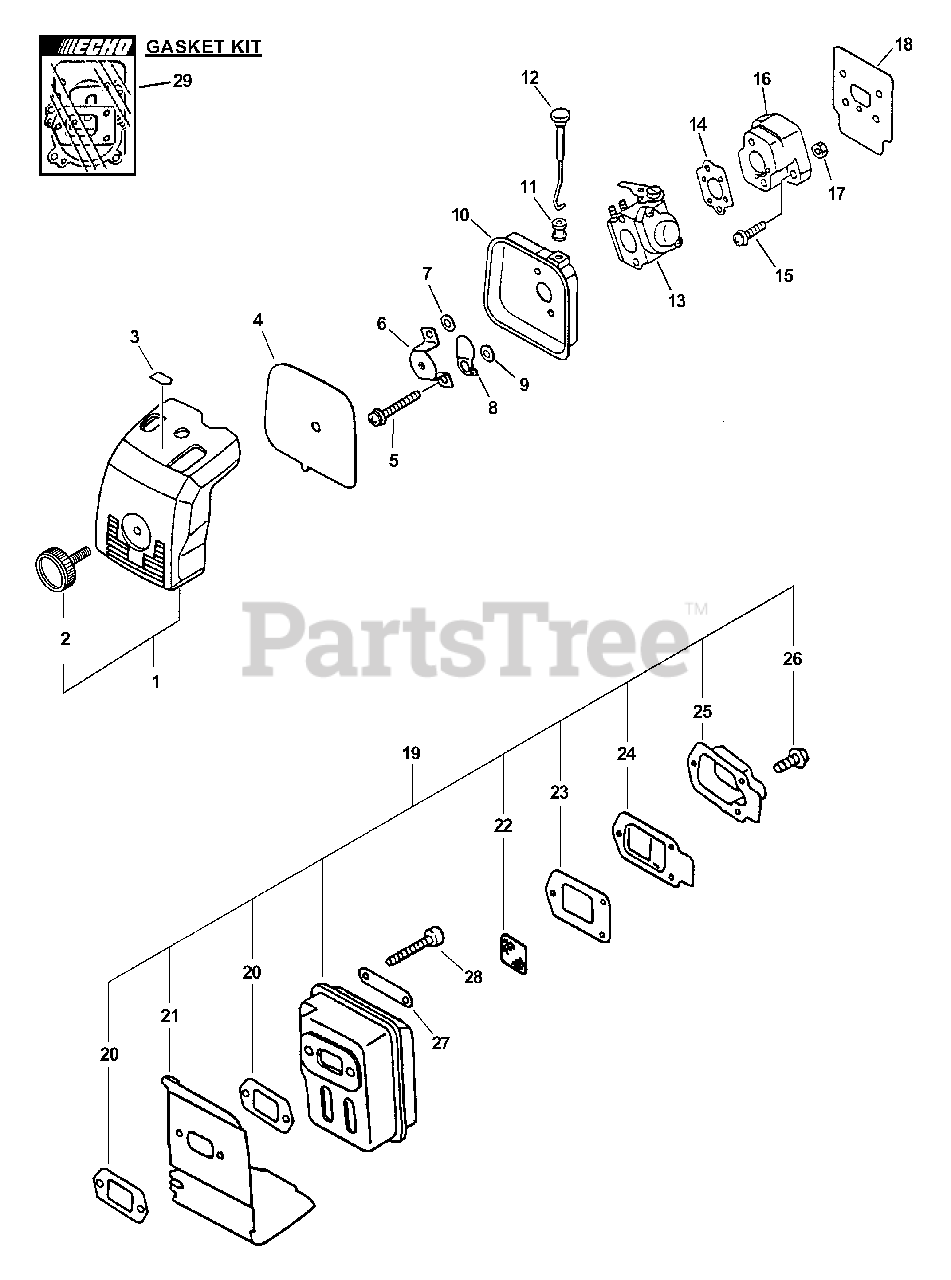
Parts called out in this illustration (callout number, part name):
1	AIR FILTER COVER ASSY
2	THUMBSCREW
3	LABEL, CHOKE
4	FILTER, HEAVY-DUTY AIR
5	SCREW 5×57
6	PLATE, PREVENT
7	WASHER, FLAT 5.5×10×0.8
8	SHUTTER, CHOKE
9	WASHER 5.2×8×0.8T
10	CASE, AIR FILTER
11	GROMMET, CHOKE
12	ROD, CHOKE
13	CARBURETOR - WT-424A
14	GASKET, CARBURETOR
15	SCREW 5×20
16	INSULATOR, INTAKE
17	NUT M5
18	HEAT SHIELD, INTAKE
19	MUFFLER ASSY
20	GASKET, EXHAUST
21	HEAT SHIELD, EXHAUST
22	SCREEN, SPARK ARRESTER
23	GASKET, EXHAUST
24	GUIDE, EXHAUST
25	OUTLET, EXHAUST
26	SCREW 4×10
28	BOLT 5×55
29	GASKET KIT
